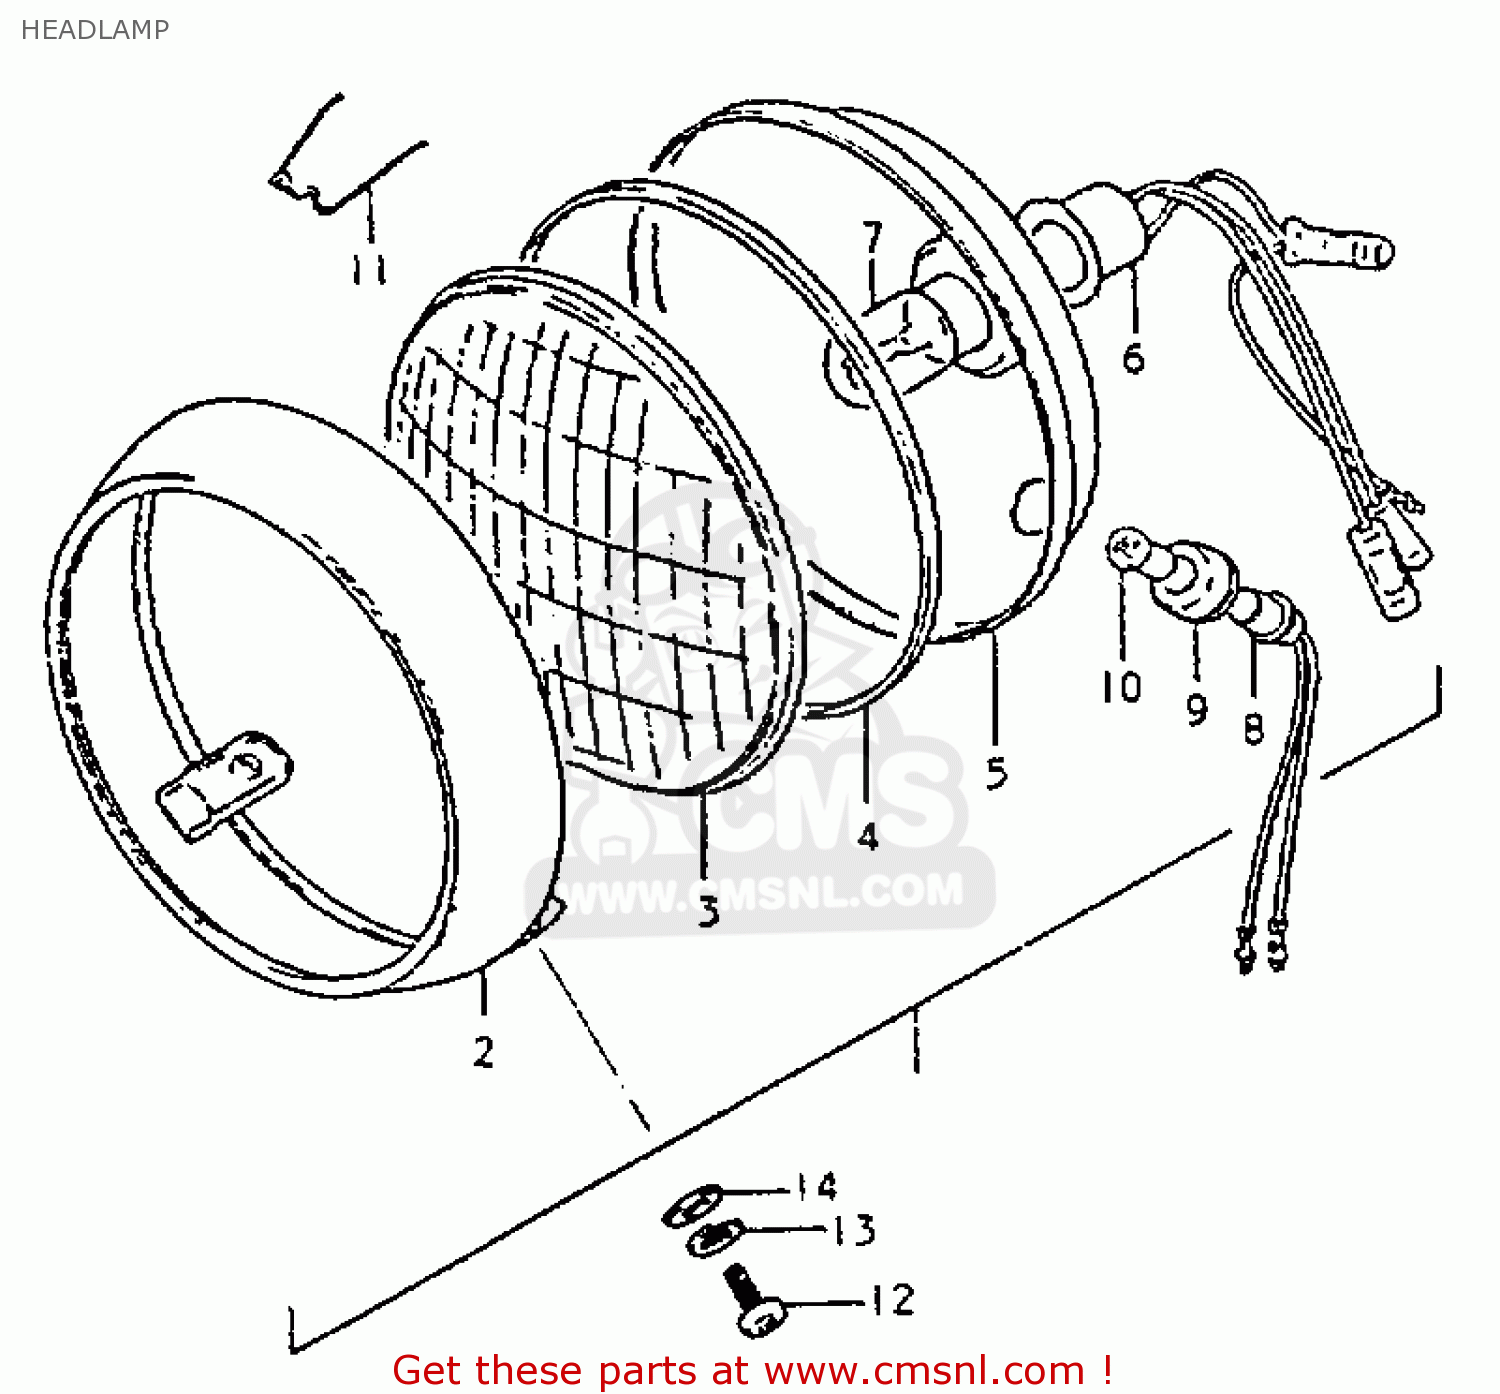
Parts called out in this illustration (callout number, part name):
1	HEADLAMP
2	RIM,HEADLAMP
3	LENS
4	GASKET (NAS)
5	REFLECTOR
6	SOCKET
7	BULB (7V,18/18W)
8	SOCKET
9	JOINT,RUBBER
10	BULB(6V/3W)
11	SPRING
12	SCREW
13	LOCK WASHER
14	WASHER
